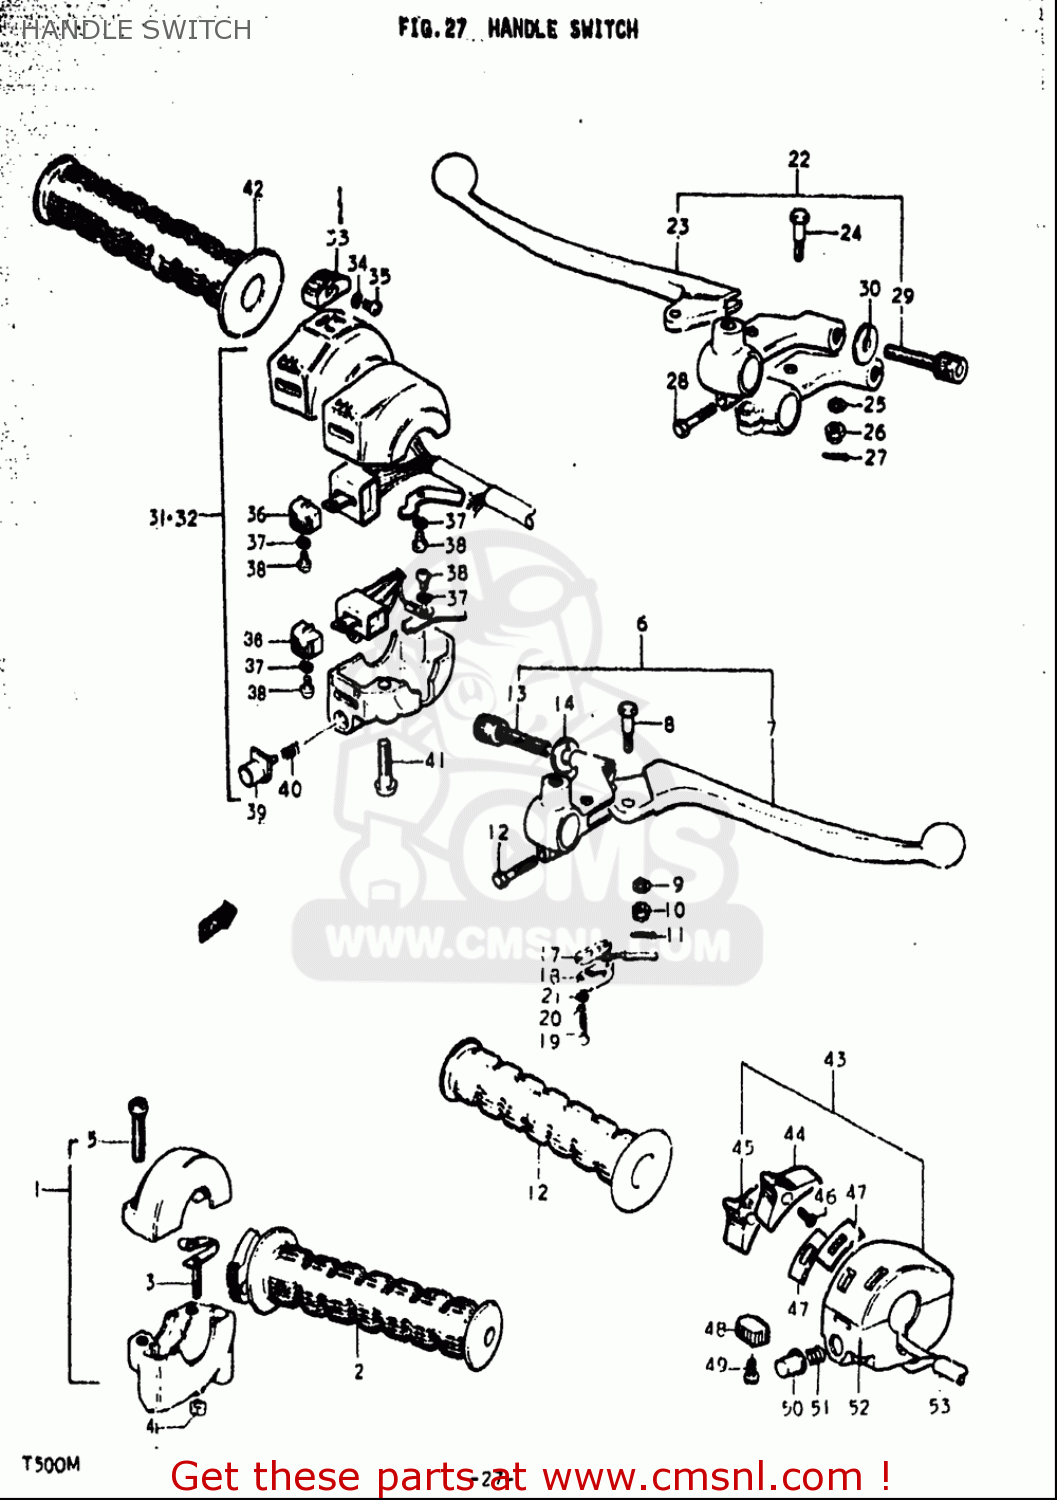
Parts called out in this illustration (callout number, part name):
2	GRIP,THROTTLE
3	ADJUSTER, THROTTLE
4	NUT
5	SCREW
6	BRAKE LEVER & SWITCH ASSY
7	LEVER,BRAKE
8	BOLT,LEVER PIVOT
9	WASHER,LOCK
10	NUT,LEVER FITTNG
11	PIN 16X20
12	BOLT
13	ADJUSTER,CABLE
14	NUT,CABLE ADJUSTER
18	COVER,FR BK TERMINAL BASE
19	SCREW
20	WASHER,LOCK
21	WASHER
22	LEVER ASSY,CLUTCH
23	LEVER,CLUTCH
24	BOLT,LEVER PIVOT
25	WASHER,LOCK
26	NUT,LEVER FITTNG
27	PIN 16X20
28	BOLT
29	ADJUSTER,CABLE
30	NUT,CABLE ADJUSTER
33	KNOB
34	WASHER,LOCK
35	SCREW
36	KNOB,HANDLE SWITCH,UPPER
37	WASHER,LOCK
38	SCREW
39	BUTTON,HORN
40	SPRING,BUTTON
41	SCREW(5X27)
42	GRIP
45	KNOB
46	SCREW
47	PLATE,SWITCH KNOB
49	SCREW
50	BUTTON,HORN
51	SPRING,BUTTON
52	SCREW
